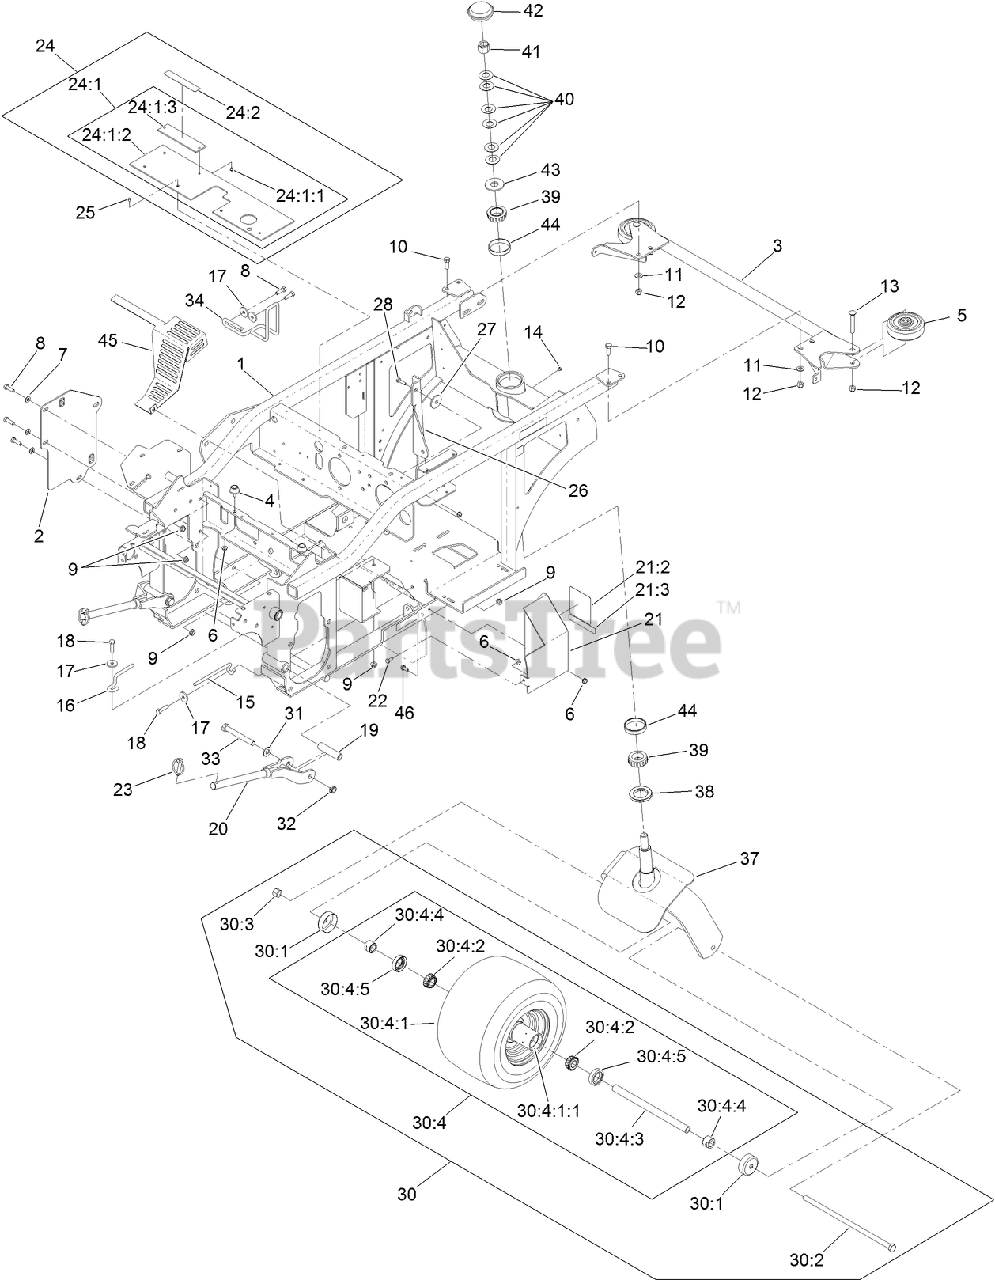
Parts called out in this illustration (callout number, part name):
1	FRAME ASM
2	PLATE-SUPPORT
3	BUMPER-REAR
4	BUMPER-RUBBER
5	ROLLER-BUMPER
6	NUT-HF
7	WASHER-PLAIN
8	SCREW-HH
9	NUT-HF
10	SCREW-HH
11	WASHER-FLAT
12	NUT-LOCK, NI
13	SCREW-CARR
15	GUIDE-BELT
16	GUIDE-BELT
17	WASHER
18	SCREW-HH
19	SPACER-WHEEL, SHORT
20	ROD-PUSH
21	DRIVE SHIELD ASM
21:2	DECAL-BELT ROUTING
21:3	DECAL-WARNING
22	SCREW-HH
23	PIN-LYNCH
24	LIFT SHIELD ASM
24:1	SHIELD-LIFT
24:1:1	RIVET-POP
24:1:3	PLATE-DECAL
24:2	DECAL-WARNING
25	RIVET-POP
26	BRACE-PTO
27	WASHER
28	SCREW-HH
30	WHEEL AND AXLE ASM
30:1	GUARD-SEAL
30:2	SCREW-HH
30:3	NUT-LOCK, NI
30:4	WHEEL AND BEARING ASM
30:4:1	Deck ASM
30:4:1:1	BEARING-CUP
30:4:2	BEARING-CONE, TAPER
30:4:3	AXLE CASTER ASM
30:4:4	SPACER-NUT
30:4:5	SEAL-CASTER
31	WASHER-FLAT
32	NUT-HEX
33	SCREW-HH
34	GUIDE-BELT
37	FORK-REAR CASTER
38	SEAL-GREASE
39	BEARING-ROLLER, CONE TAPER
40	WASHER-BELLVILLE
41	NUT-LOCK, NI
42	CAP-GREASE
43	WASHER-FLAT
44	CUP-TAPERED, ROLLER BEARING
45	SHIELD-HEAT
46	SCREW-HHF
